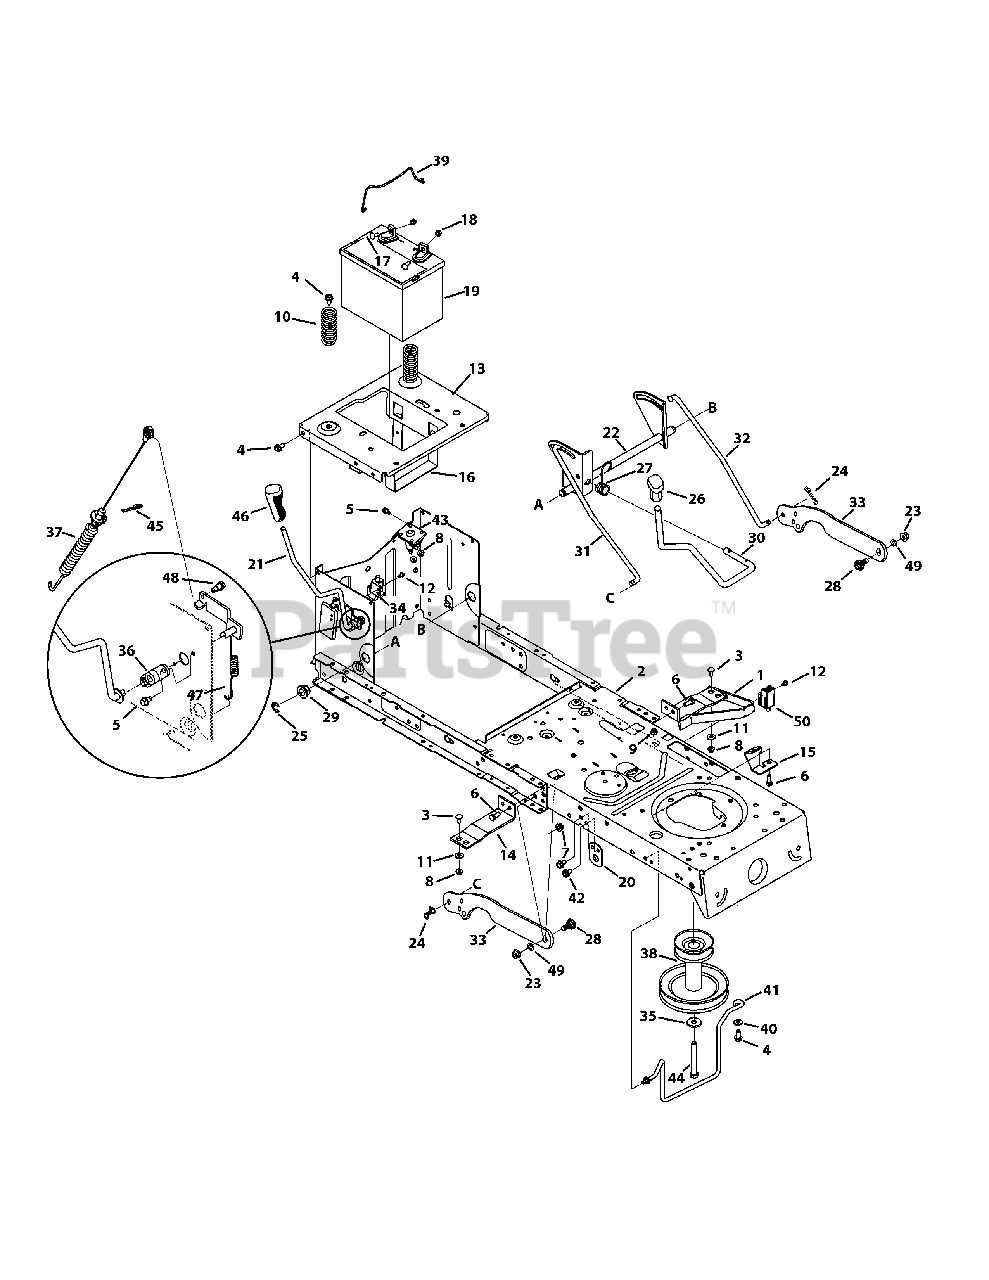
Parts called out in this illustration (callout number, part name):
1	Support Bracket
2	Frame Assembly
3	Screw Carriage, 1/4-20 x .75
4	Screw 5/16-18 x .750
5	Screw, 1/4-20 x .500
6	Hex Screw, 5/16-18 x .75
7	Flangelock Nut, 5/16-18
8	Flangelock Nut, 1/4-20
9	Hexlock Nut, 5/16-18
10	Compression Spacer, 1.314 x 2.55
11	Flat Washer, .28 x .74 x .063
12	Shoulder Spacer, 10-32 x .500
13	Seat Frame Bracket
14	Running Board Bracket
15	Support Frame Bracket
16	Battery Bracket
17	Hex Head Flange, 1/4-20 x .75
18	Sems Nut, 1/4-20
19	230 CCA Battery Dry
20	Support Bracket
21	PTO Handle & Deck Engage Cable Service Kit
22	Lift Assembly
23	Flangelock Nut, 3/8-16
24	Bow-tie Cotter Pin
26	Handle Grip, 5/8
27	Torsion Spring
28	Shoulder Bolt, 3/8-16 x .50 x .270
29	Hex Flange Bearing
30	Deck Handle, Lift, 46" Deck
31	Lift Rod, RH
32	Lift Rod, LH
34	Switch Interlock
35	Flat Washer, .450 x 1.250 x .164
36	PTO Bearing
37	Deck Engage Cable & PTO Handle Service Kit
38	Engine Pulley, 3.39 x 6.12
39	Battery Hold Down Rod
40	Flat Washer, .406 x .875 x .059
41	42" Belt Keeper
42	Screw, 5/16-18.0 x .625
43	12V Solenoid
44	Hex Screw, 7/16-20 x 3.25
45	Click Pin, .092 x 1.64
46	Handle Grip, 3/8
47	PTO Spring Extension
48	Shoulder Bolt, 1/4-28 x .342 x .335
49	Flat Washer, .385 x .62 x .063
50	Screw Mount Interlock Switch
